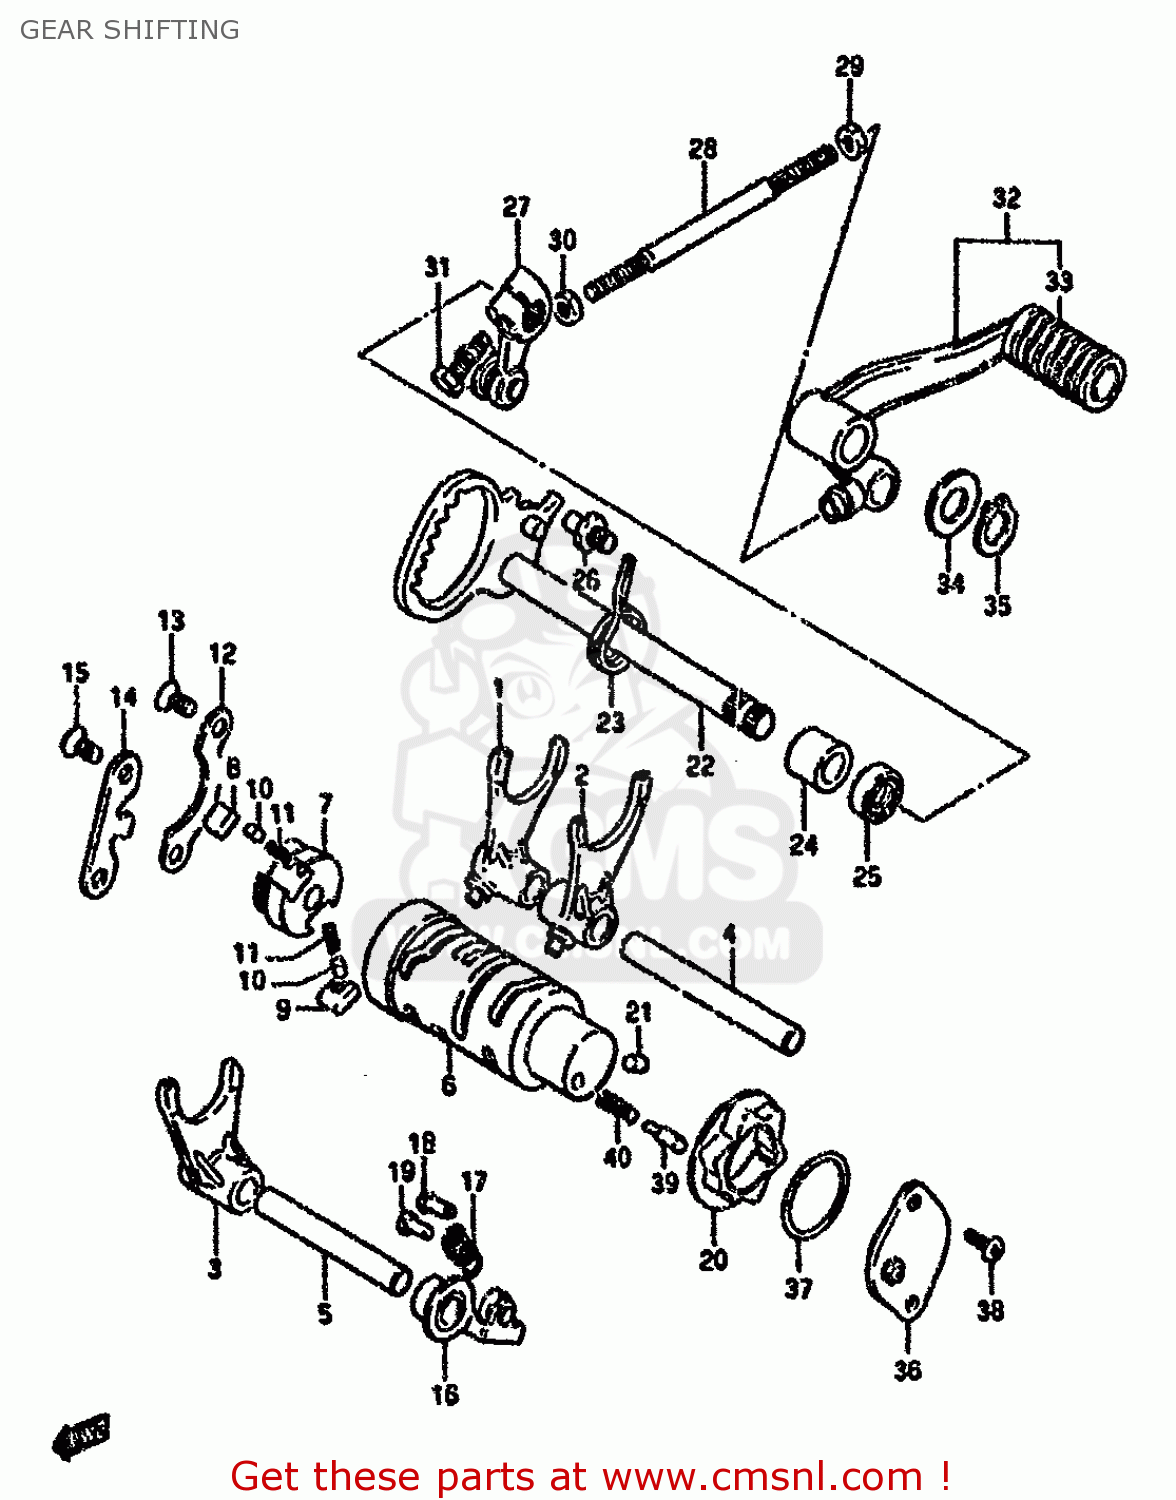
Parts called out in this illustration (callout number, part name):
1	FORK,GEAR SHIFT NO.1
2	FORK, GEAR SHIFT N-2
3	FORK,GEAR SHIFT NO.2
4	SHAFT,GEAR SHIFT FORK
5	SHAFT,GEAR SHIFT FORK
6	CAM,GEAR SHIFTING
7	GEAR,GEARSHIFT CAM DRIVE
8	PAWL,GEAR SHIFT NO.1
9	PAWL,GEAR SHIFT NO.2
10	PIN(5X8)
11	SPRING
12	LIFTER,GEAR SHIFT POLE
13	SCREW
14	GUIDE,GEAR SHIFT CAM
15	SCREW
16	STOPPER,GEAR SHIFTING CAM
17	SPRING
18	RIVET
19	RIVET
20	PLATE,GEAR SHIFT CAM STOPPER
21	PIN 4X6
22	SHAFT,GEAR SHIFTING
23	SPRING
24	SPACER(12X20X15.3)
25	OIL SEAL
26	STOPPER,GEAR SHIFT CAM
27	ARM,GEAR SHIFT LINK
28	ROD,GEAR SHIFT LINK
29	NUT
30	NUT
31	BOLT
32	LEVER ASSY,GEAR SHIFTING
33	RUBBER,PEDAL
34	WASHER(12.5X20X1)
35	CIRCLIP,12 MM
36	BODY,GEAR SHIFT SWITCH
37	O-RING (D:2.4 ID:26.2)
38	SCREW
39	PIN(5X15.5)
40	SPRING
